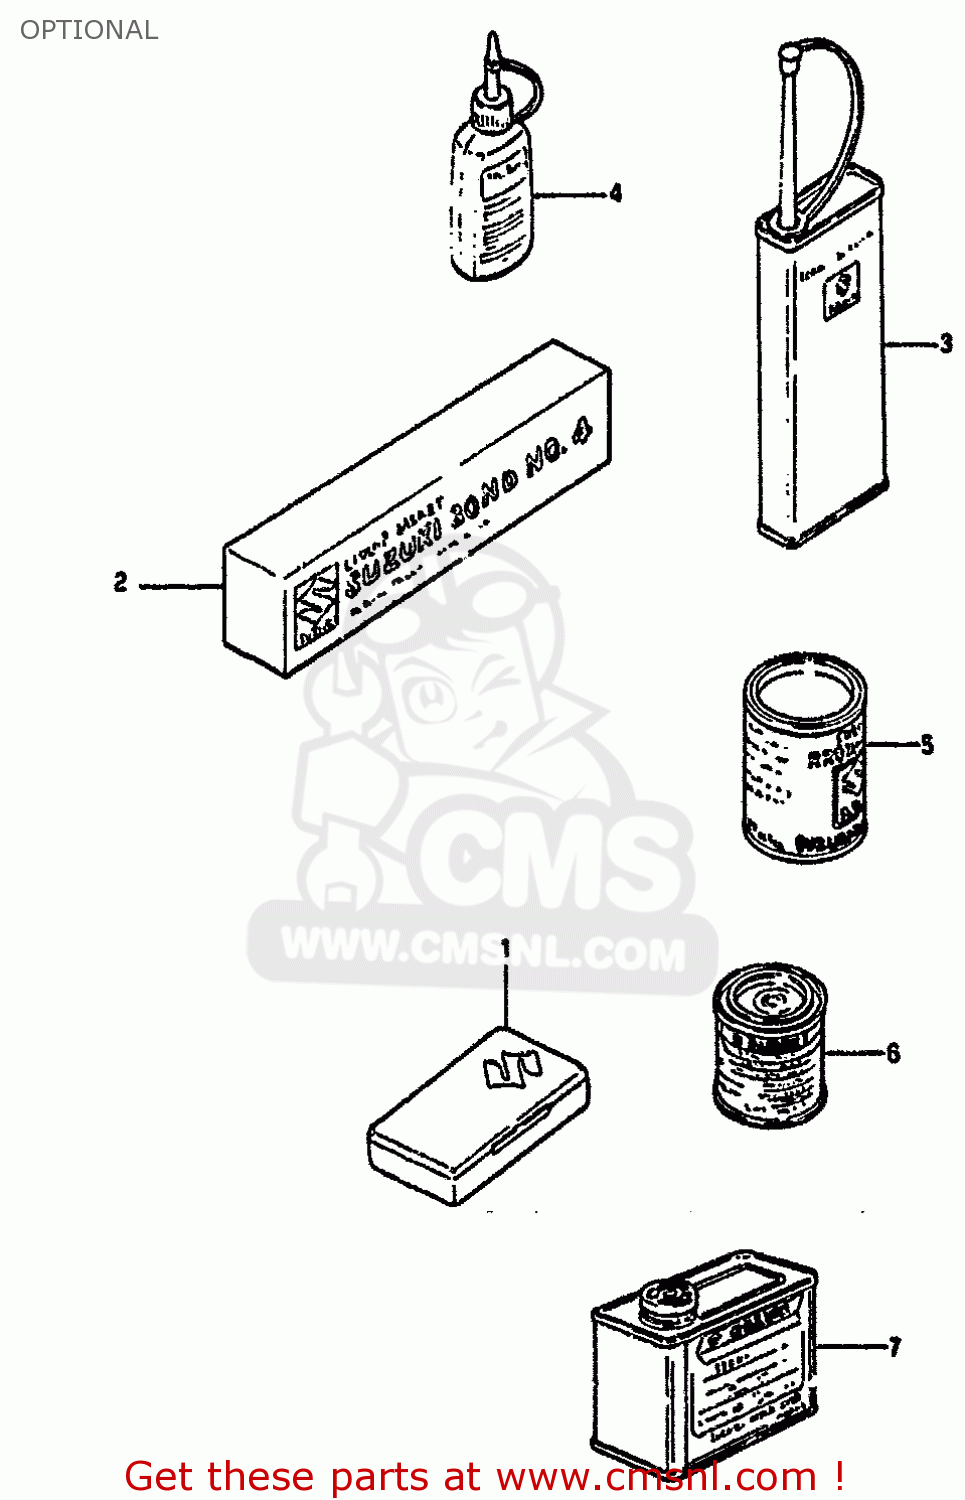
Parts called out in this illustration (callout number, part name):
1	TUBE REPARING TOOL
2	BOND 1104
3	THREAD LOCK NO.1401 CLEAR 200G
4	THREAD LOCK NO
5	GREASE(C)EP2 LITHIUM 150G
6	PAINT BLIGHT S
7	PAINT (CHAMPION BLUE)
